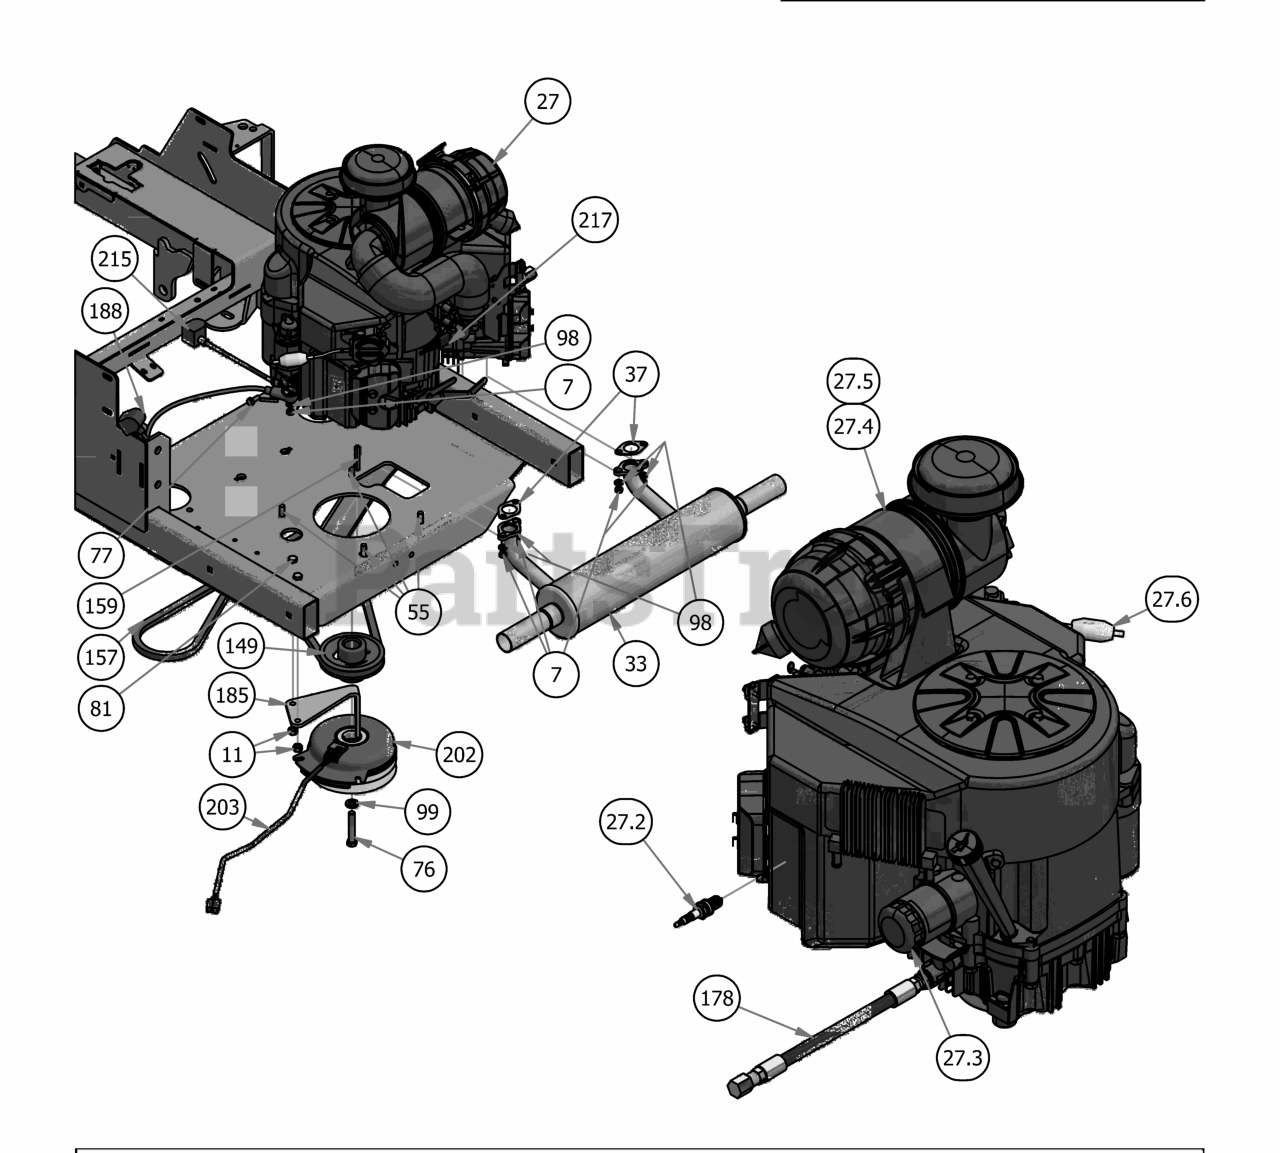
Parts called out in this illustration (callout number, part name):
7	M8-1.25 Zinc Nut
11	3/8" Hex Nut
27	Kawasaki FX850 Engine
27.2	Spark Plug - Kawasaki
27.3	Oil Filter
27.4	Canister Air Filter- Inner
27.5	Canister Air Filter- Outer
27.6	Universal Inline Fuel Filter
33	2019 Rebel/Rogue Kawasaki 850 Muffler
37	Exhaust Gasket
55	3/8 x 1 1/8 bolt
76	7/16" x 2 1/2" Hex Bolt
77	M8x1.20x20MM Hex head bolt
81	3/8" x 1" Hex Bolt
98	5/16" Lock Washer
99	7/16" Lock Washer
149	4 3/4 Motor Pulley
157	2019 Rogue Pump Belt 68"
159	1/4 x 2 Square key Stock
178	Kawasaki Oil Drain
185	PTO Engager Holder
188	24" Red Battery Cable
202	Clutch Assembly
203	Clutch Pigtail
204	2019 Veritical Suspension Frame
215	Starter Cable
217	Kawasaki Harness Adapter
